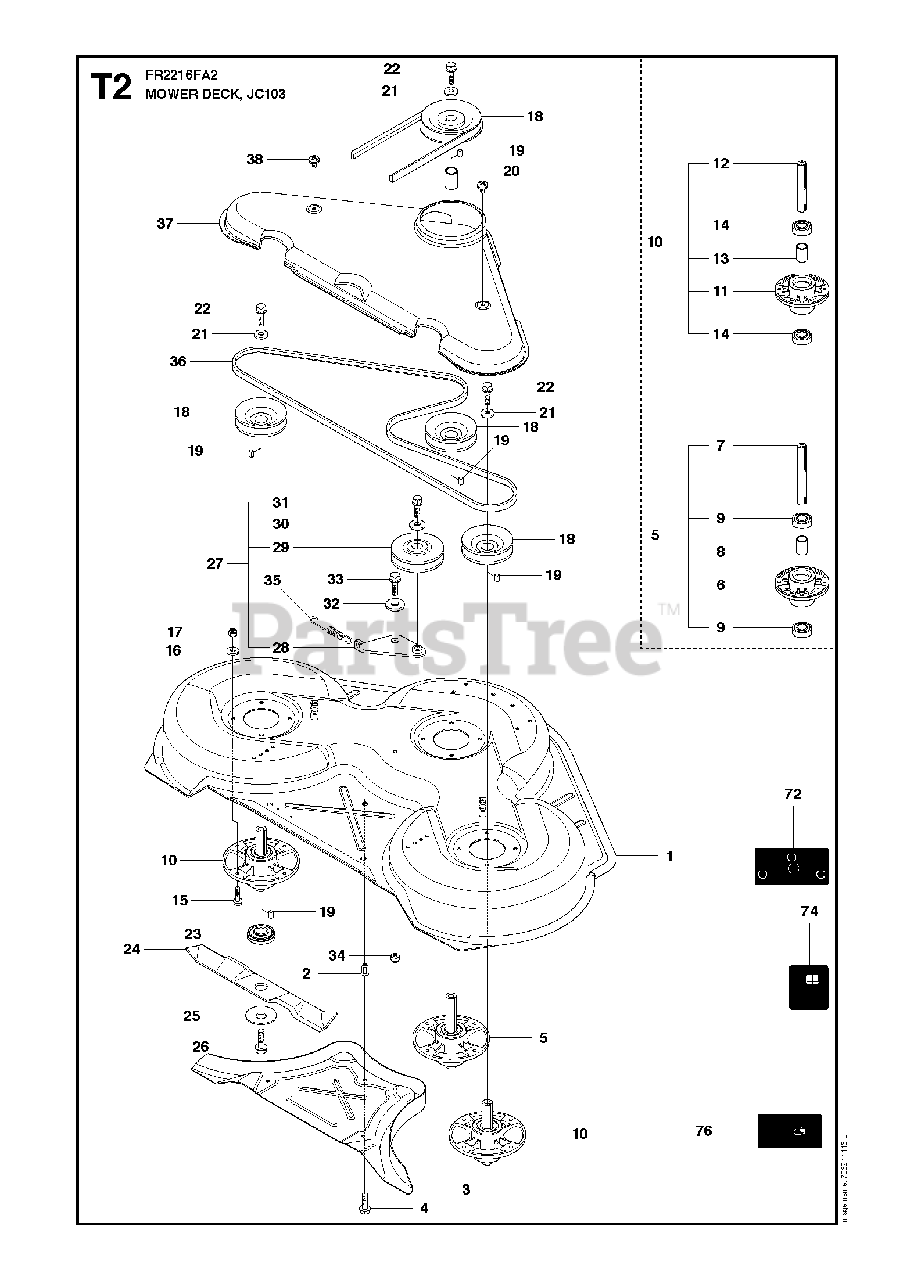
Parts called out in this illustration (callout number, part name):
5	RP SPINDLE ASSY
6	BEARING HOUSING
7	SHAFT
8	SPACER
9	BEARING
10	RP SPINDLE ASSY
11	BEARING HOUSING
12	AXLE
13	SPACER
14	BEARING
16	WASHER BRB 8.4X17
17	LOCKNUT M8
24	BLADE
27	BELT TENSIONER ASSY
28	BELT TENSIONING ARM
29	PULLEY
30	SPACER
31	BOLT
32	WASHER
34	LOCKNUT M8
36	BELT
